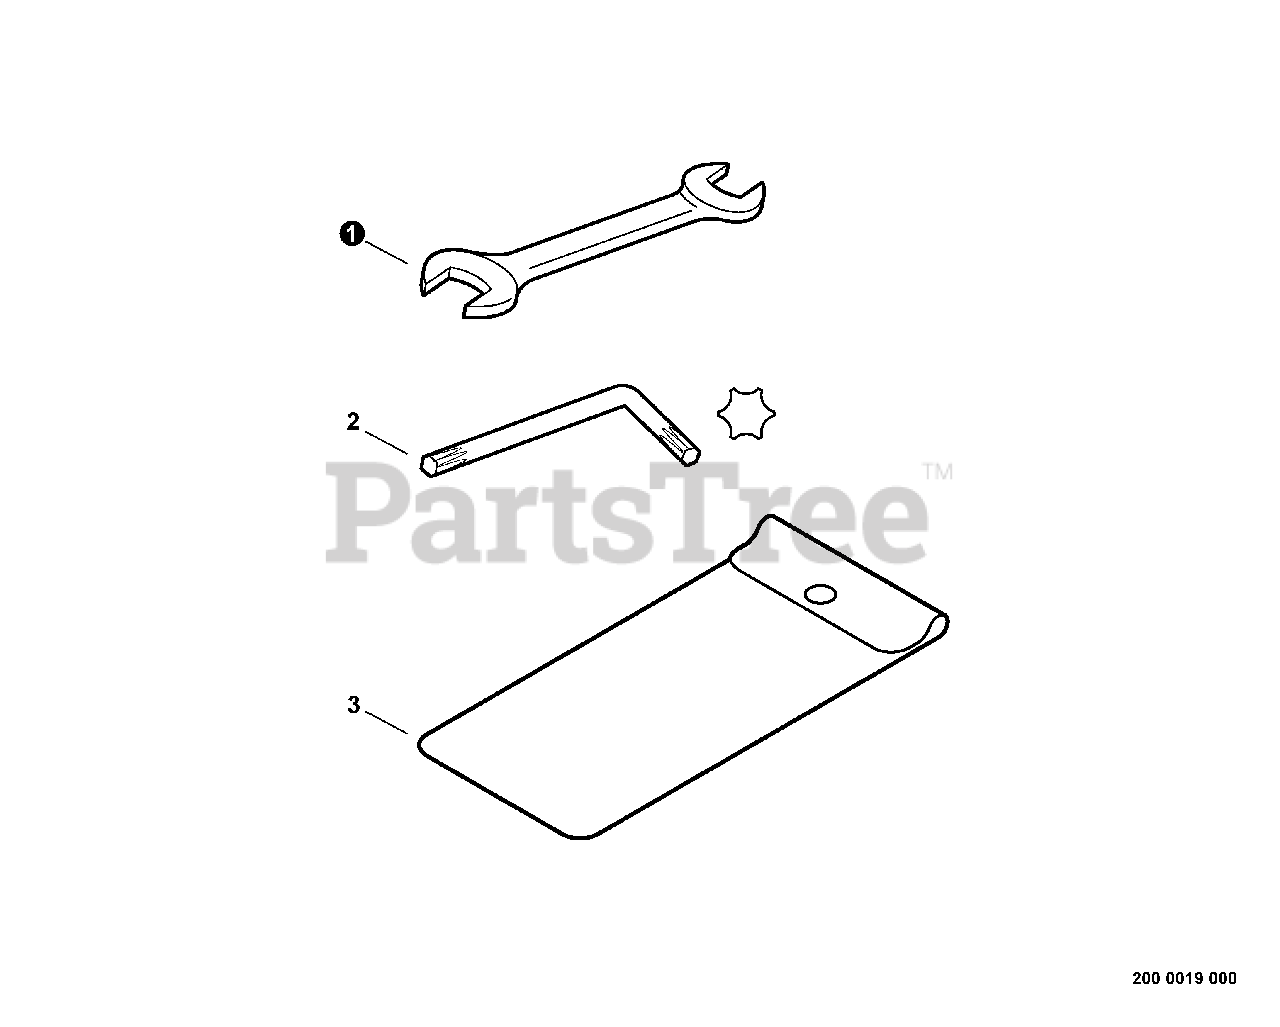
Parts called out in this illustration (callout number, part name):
1	SPANNER - 8X10mm
2	KEY - TORX -- T27
3	BAG, TOOL
